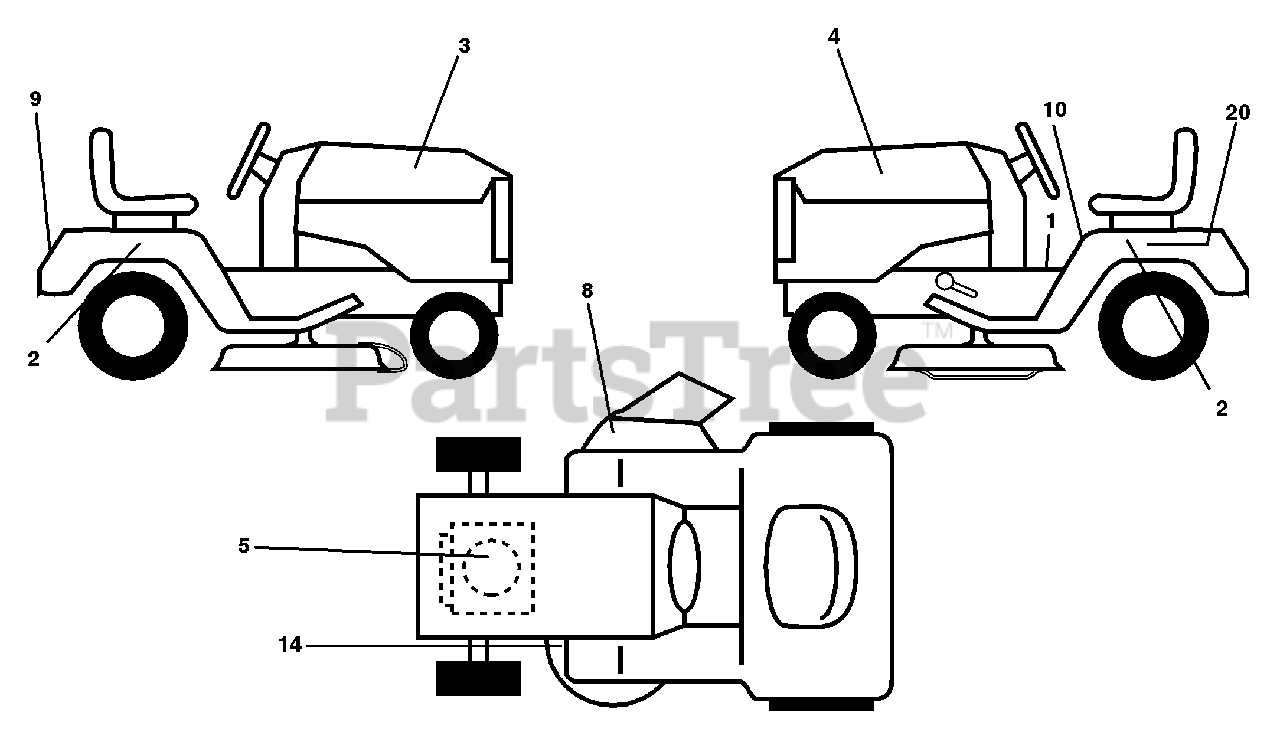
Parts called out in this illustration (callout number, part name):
1	Decal Oper Step Thru Eng/Fr
2	Decal Fender Auto Husq. Radius
3	Decal Hood RH
4	Decal Hood LH
5	Decal HP Engine
8	Decal Warning
9	Decal Fender Husq
10	Decal Fender Danger Eng/Fr
14	Decal V-Belt Schematic
20	Decal Bat Dan/Psn
